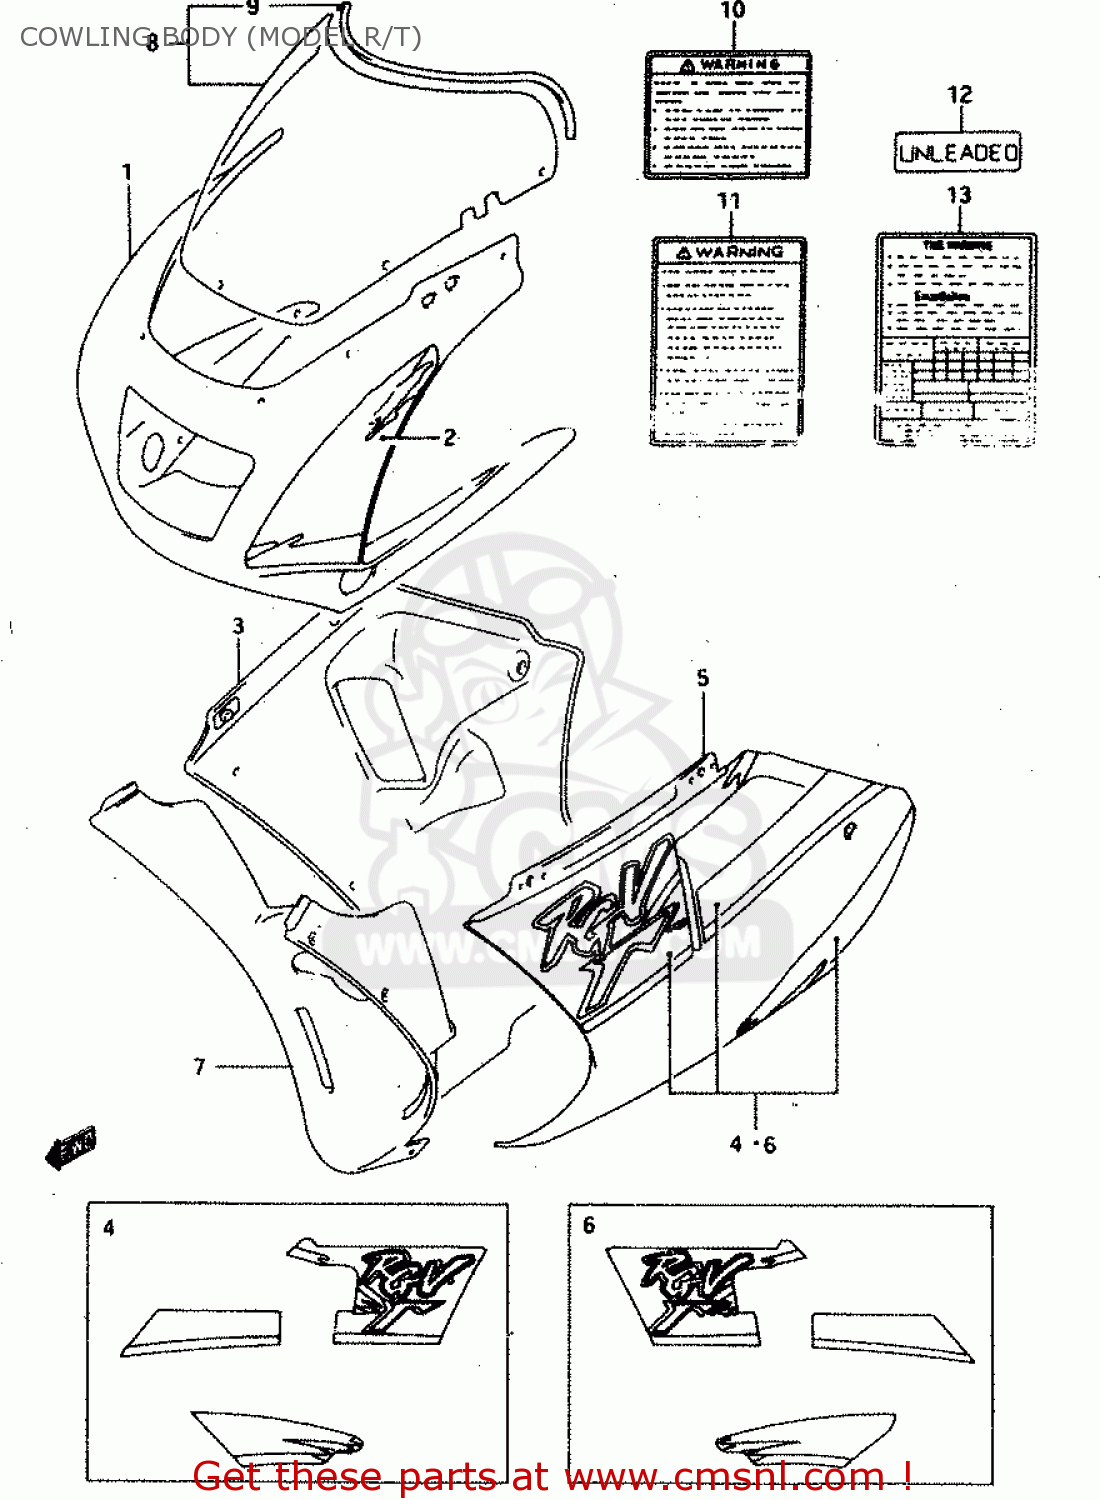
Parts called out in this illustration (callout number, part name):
1	COWLING ASSY,BODY
2	TAPE SET, BODY
3	COWLING ASSY,UNDER,R
4	TAPE SET, UNDER RH
5	COWLING ASSY,UNDER,L
6	TAPE SET,COWL UNDER,L
7	COWLING,UNDER CTR
8	SCREEN SET,WIND
9	MOLDING WINDSCREEN
10	LABEL
11	LABEL (WARNING SCREEN)
12	LABEL,CAUTION
13	LABEL, TIRE AIR PRESSURE
